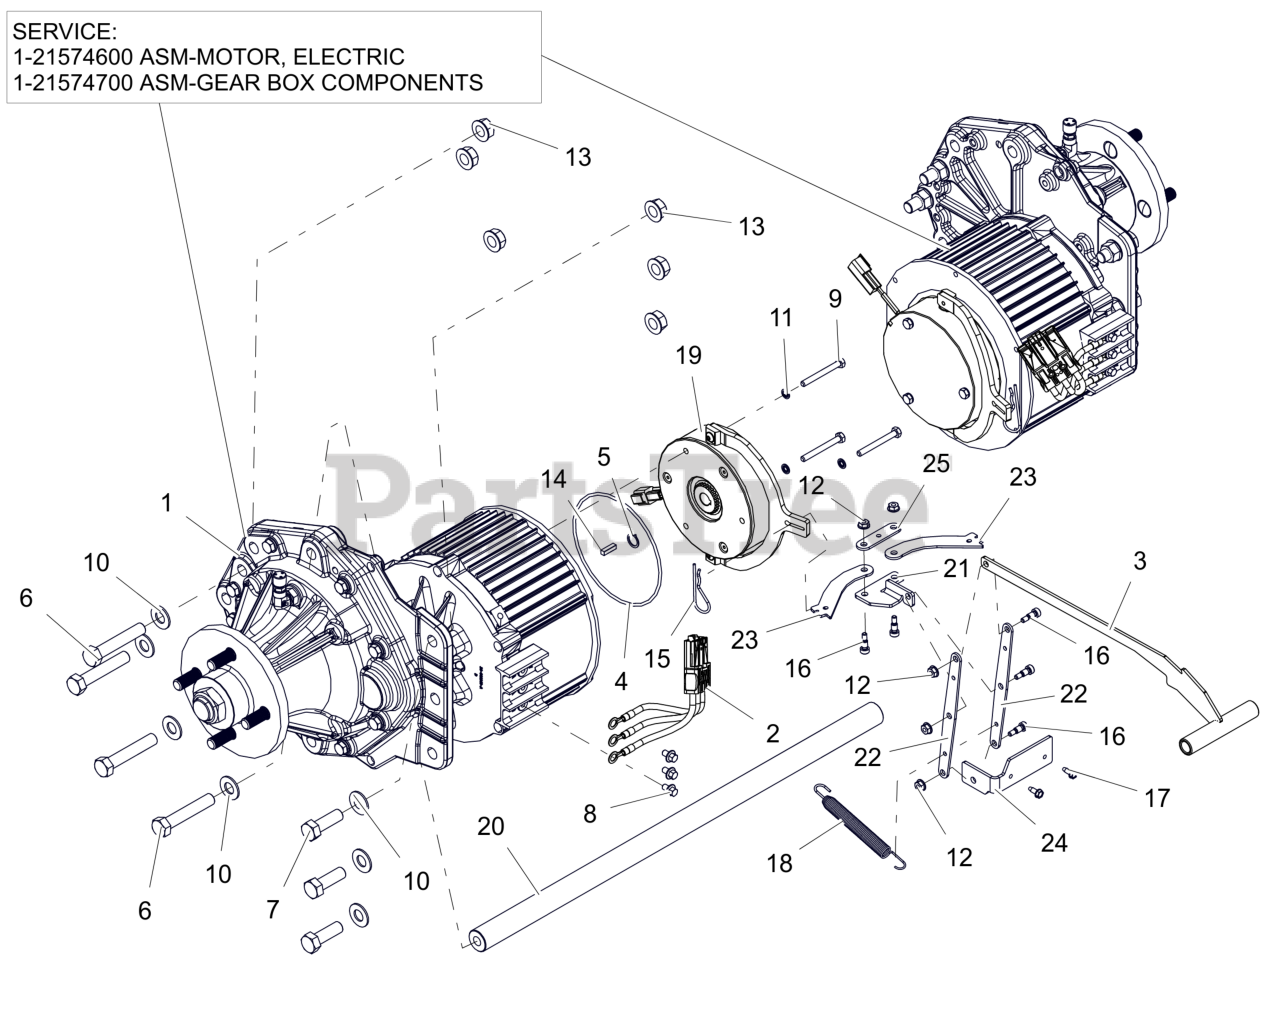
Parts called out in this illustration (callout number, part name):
1	ASM, WHEEL DRIVE
1	ASM-MOTOR, ELECTRIC
1	ASM-GEAR BOX COMPONENTS
2	HARNESS, PHASE - DRIVE MOTOR
3	WLDMT, BRAKE RELEASE
4	O-RING 126MM IDX3MM
5	RING, RETAINING-EXTERNAL 25MM X 1.2MM
6	BLT, HEX .50-13X2.75 G8 ZCC
7	BLT, HEX 0.5-13X1.5 GR8 ZCC
8	BLT,HEX M6-1X10 G8.8 ZCC
9	BLT,HEX M6-1X55 EP30 G8.8 ZCC
10	WSHR, FLT .557X1.040X.102 ZCC
11	WSHR-FL-STL, SEAL 6MMX11MMX1MM
12	NUT, FLG-TOP LK #10-24 GRF ZCC
13	NUT, FLG-CTR LK .500-13 GG ZCC
14	KEY-STR 5X5X18MM RD ENDS
15	PIN, HAIR-#7 .094X2.31 ZC120
16	BLT-SHLDR .25X.375
17	SCR,TAP #10-24X.50 HWH TR ZCC
18	SPRING, SWIVEL HOOK EXTENSION
19	BRAKE, MOTOR
20	SHAFT, TRANSAXLE SUPPORT (BLACK)
22	LINK, MIDDLE
23	LINK, PUSH
24	PIVOT, BRAKE LINK MAIN
25	PLATE, BRAKE PULL DOUBLER
